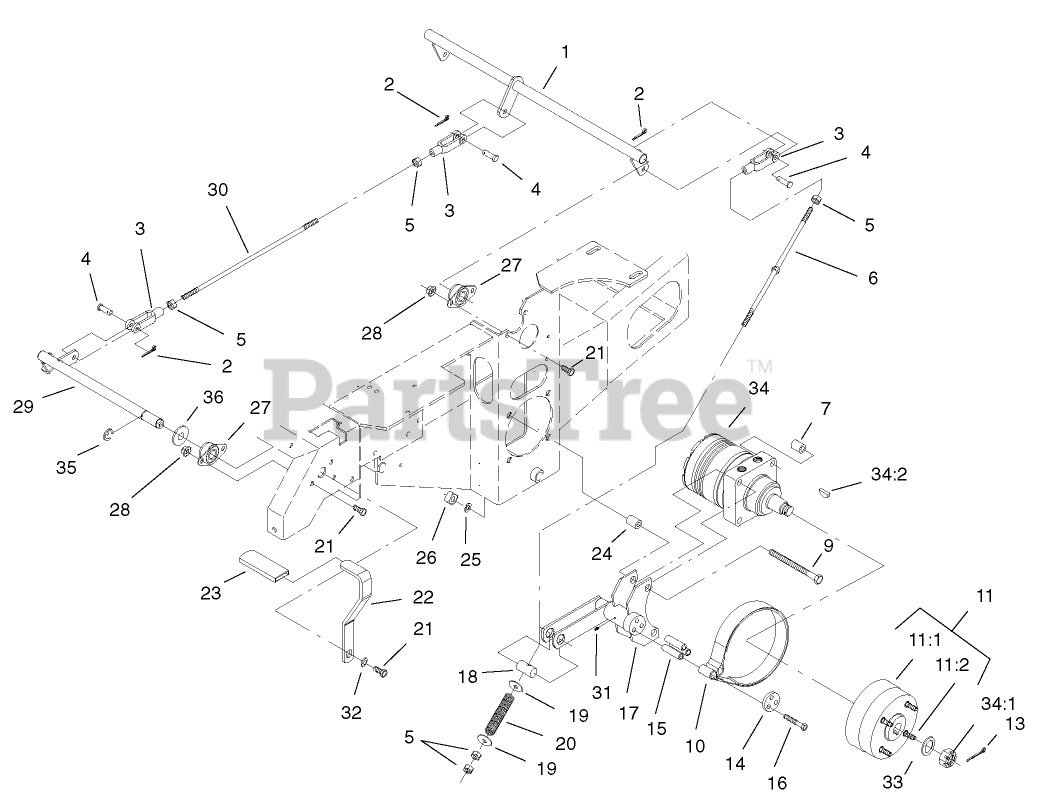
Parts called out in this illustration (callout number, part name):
1	CRANK-BRAKE, PARK
2	PIN-COTTER
3	YOKE-LINKAGE, BRAKE
4	PIN-CLEVIS
5	NUT-HEX
6	ROD-BRAKE
7	SPACER-WHEEL
9	SCREW-HH
10	BAND-BRAKE
11	WHEEL HUB ASM
11:1	HUB-WHEEL
11:2	STUD-WHEEL
13	PIN-COTTER
14	RETAINER-BAND, BRAKE
15	SPACER
16	SCREW-HH
17	BRACKET-BRAKE
18	PIN-TRUNION
19	WASHER-FLAT
20	SPRING-BRAKE
21	SCREW-HH
22	HANDLE-BRAKE, PARK
23	GRIP-LEVER
24	SPACER-WHEEL
25	WASHER-LOCK
26	NUT-SQUARE
27	BEARING-FLANGE, SIDE
28	NUT-HHF, WHIZ
29	SHAFT-BRAKE, PARKING
30	LINKAGE-HANDLE, BRAKE
31	FITTING-GREASE
32	WASHER-BELLEVILLE
33	WASHER-SPACER
34	MOTOR-WHEEL
34:1	NUT-HH
34:2	KEY-WOODRUFF
35	E-RING
36	WASHER-FLAT
